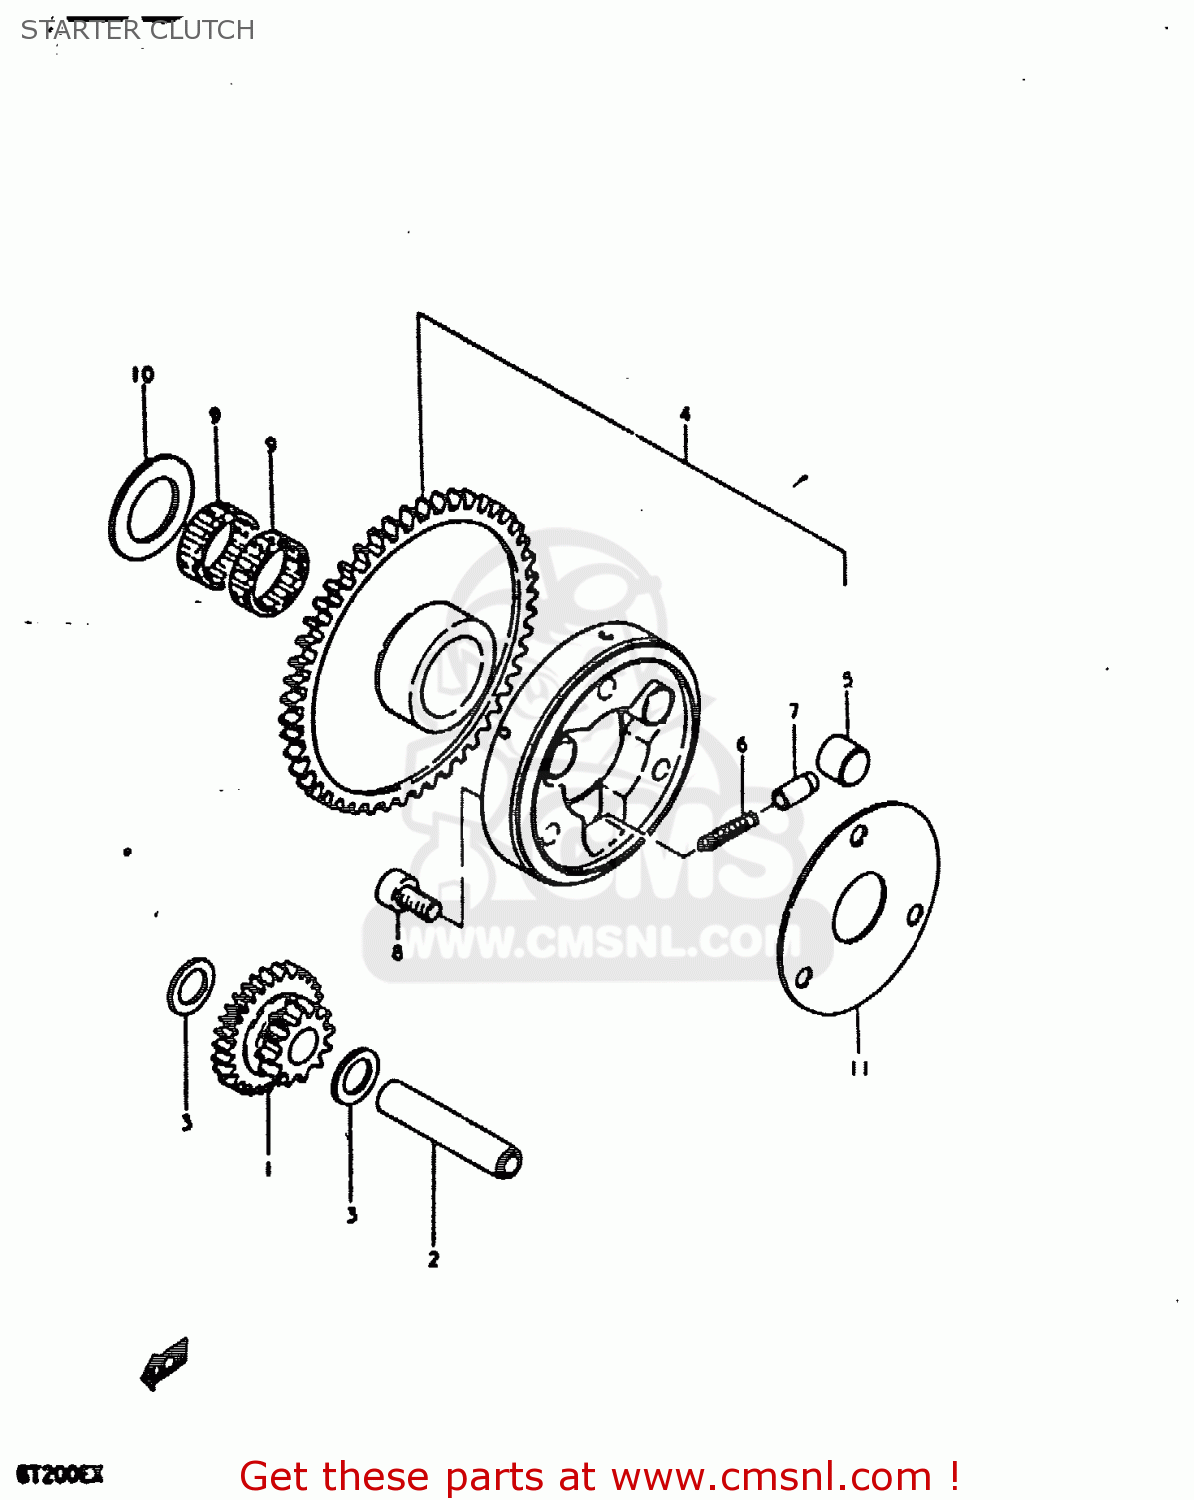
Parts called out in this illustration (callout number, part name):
1	GEAR, STARTER IDLE
2	PIN(7.4X13X56)
3	WASHER
4	STARTER CLUTCH SET
5	ROLLER(15X13)
6	SPRING
7	PIECE,PUSH
8	BOLT
9	BEARING(25X29X9.9)
10	WASHER
11	SHIM,STARTER CLUTCH HUB
